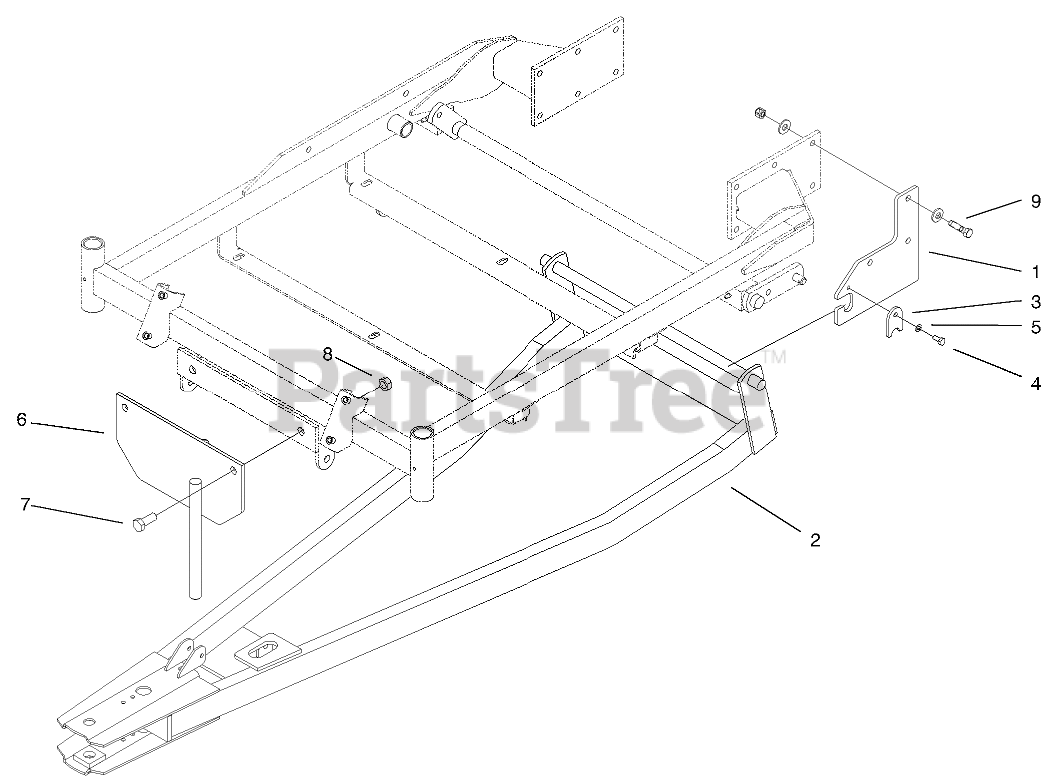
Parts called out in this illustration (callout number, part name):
1	PLATE-SUPPORT
2	FRAME-BLADE
3	PLATE-RETAINER
4	SCREW-HH
5	WASHER-LOCK
6	PLATE-PULLEY
7	SCREW-HH
8	NUT-HEX
9	SCREW-HH
